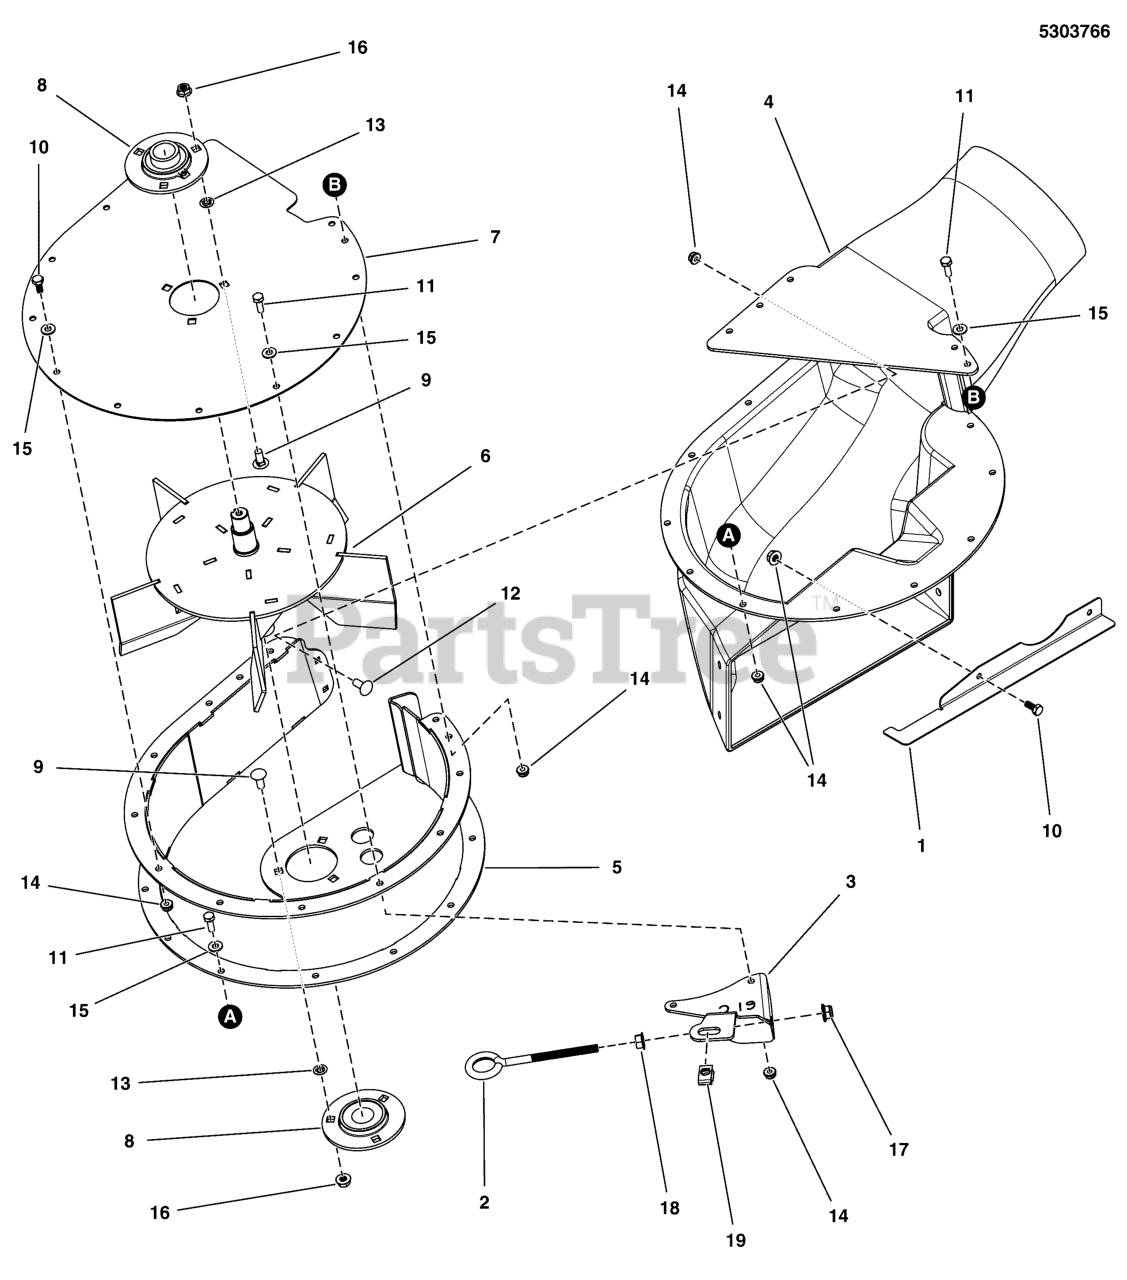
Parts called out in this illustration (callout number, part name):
1	BRACKET, ADAPTER SEAL, COM BLOWER - BLK
2	EYE BOLT, 3/8-16 X 6, 3THRD, 1EYE, CZ
3	WELD, SPRING ANCHOR, COM - BLK
4	MOLDED HOUSING, COMMERCIAL TURBO VAC
5	WELD, FAN CAGE, BLOWER - BLK
6	KIT, T-MAX FAN UPDATE
7	PLATE, FAN, TOP - BLK
8	BEARING, FLANGE, 1" BORE
9	BOLT, 5/16-18 X 3/4, CARRIAGE
10	HHCS, 1/4-20 X 0.625, GR5, ZINC/CLEAR
11	BOLT, 1/4-20 X 3/4 GD5 CZ
12	BOLT,1/4-20X0.750,GR5,STD NECK,SQ,ZC/CL
13	5/16 PUSH-ON NUT RETAINER, STL, CZ
14	NUT, 1/4-20 HEX NYLOCK FLANGE
15	WASHER, 1/4 SAE
16	NUT, 5/16-18 HEX SERRATED FLANGE (SMALL)
17	NUT, 3/8-16 HEX NYLOCK FLANGE
18	NUT, 3/8-16 HEX SERRATED FLANGE
19	BODY CLIP, 5/16-18-7GA MATERIAL
